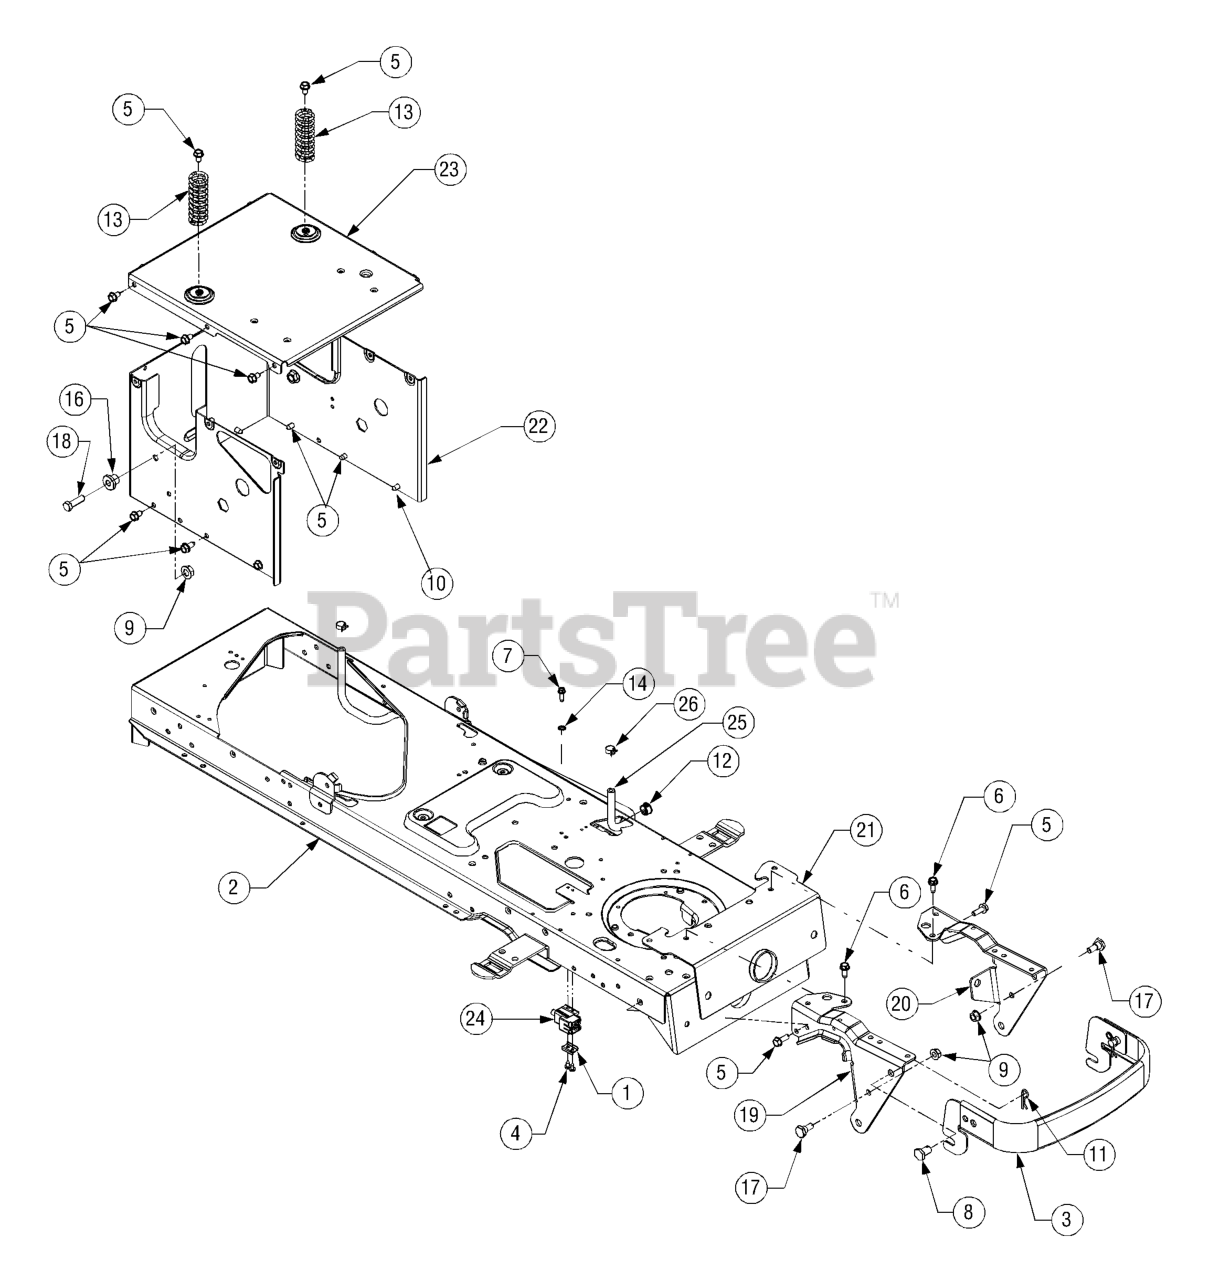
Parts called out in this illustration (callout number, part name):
1	Plate, Switch
5	Screw, Self-tapping, 5/16-18, 0.75
6	Screw, 5/16-18, 0.750
7	Screw, Hex Wash. Hd. Tapp, 1/4-20 x 0.625
8	Pin, Clevis, .50 Dia x .78 Lg
9	Nut, Nylon Lock, 3/8-16
10	Screw, Hex Wash. Tapp, 5/16-18 x .5
11	Pin, Internal Cotter
12	Snap Bushing
13	Spring, Compression, 1.28 OD x 3.125 Lg
14	Washer, Lock, Ext 1/4
16	Shoulder Spacer
17	Shoulder Screw, 3/8-16
18	Hex Screw 3/8-16 x 1.25
25	Fuel Line
26	Clamp, Hose, .490 Dia.
